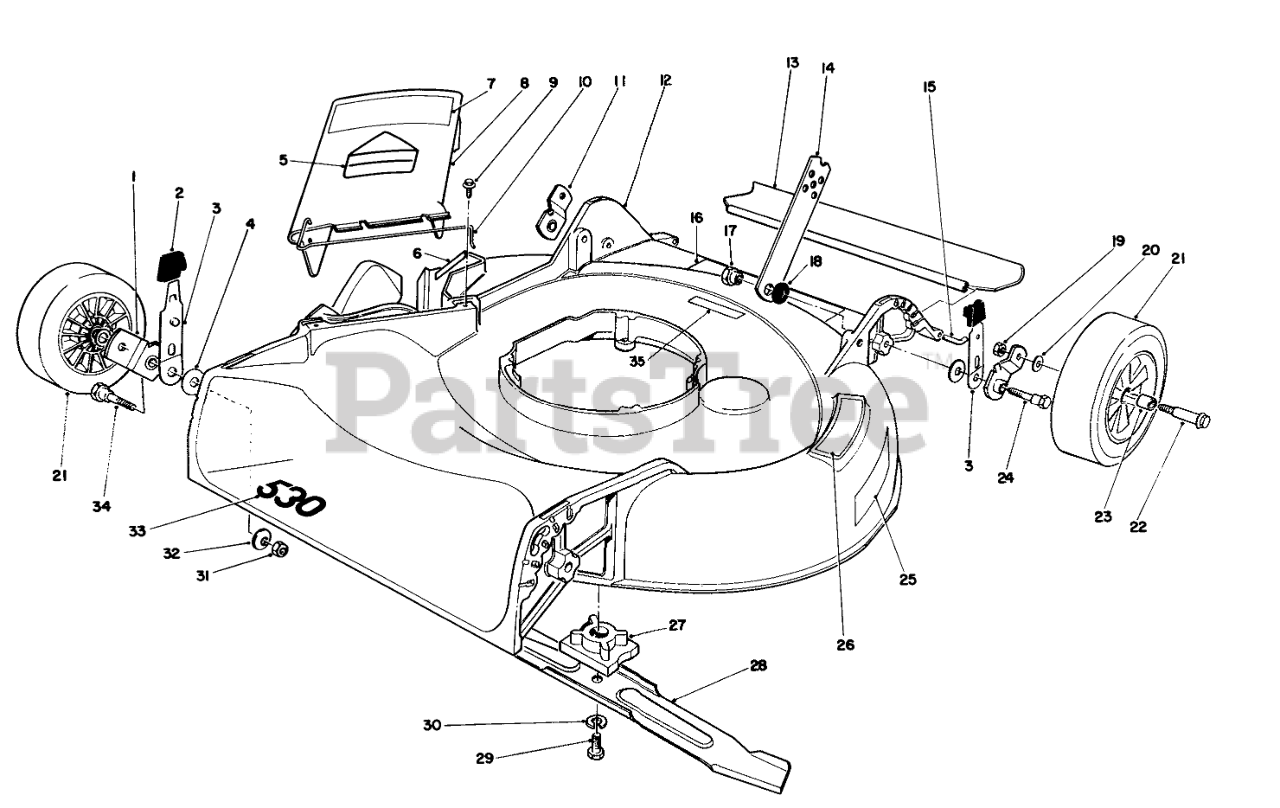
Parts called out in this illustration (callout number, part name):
1	Pivot Arm
2	KNOB-ARM
3	SPRING ARM ASM
4	WASHER-PIVOT
5	DECAL-DANGER
6	Decal-Danger
7	Decal-Danger(French)
8	Deflector Assembly (Incl. Ref. #5, 7 & 9)
9	SCREW-HWH
10	SPRING HINGE
11	Pivot Arm
12	HOUSING/DECAL
13	REAR SAFETY SHIELD 21
14	HANDLE LATCH
15	SHIELD ROD
16	Danger-Decal
17	HANDLE PIVOT NUT
18	SPACER
19	Nut
20	WASHER
21	Wheel & Tire Assembly (Incl. Ref. #23)
22	BOLT-WHEEL
23	BUSHING
24	PIVOT SCREW
25	Decal-Step
26	STEP PAD DECAL
27	BLADE RETAINER
28	Blade
29	SCREW-HH
30	WASHER-LOCK
31	NUT-LOCK, NI
32	WASHER-BELLEVILLE
33	Decal-530
34	5/16-18 PIVOT SCREW
35	Decal
